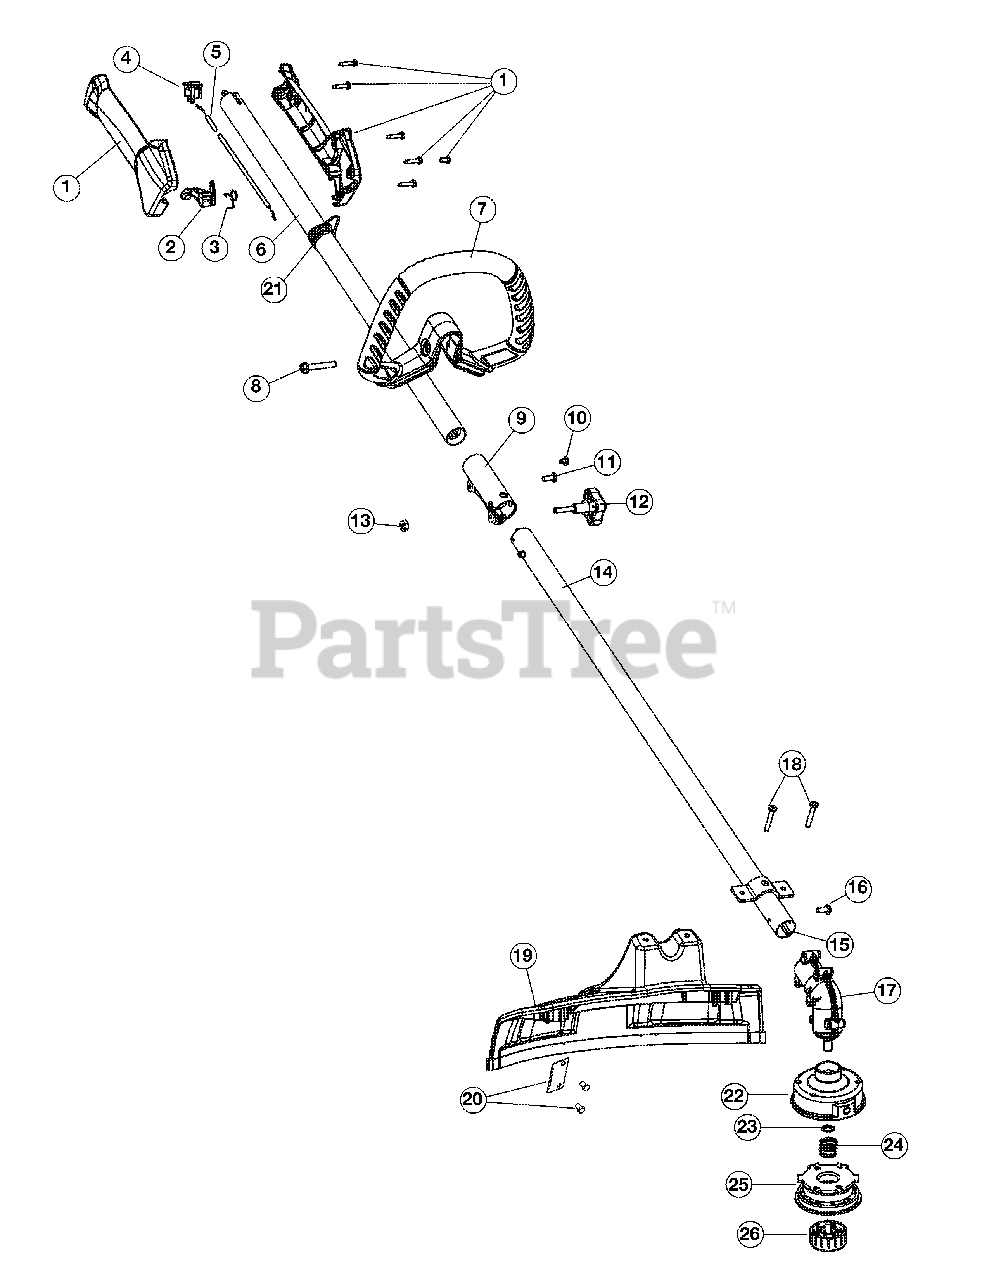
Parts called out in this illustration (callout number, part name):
1	Throttle Housing Assembly (Incl. Ref No. 2-4)
2	Throttle Trigger
3	Throttle Trigger Spring
5	Throttle Cable Assembly
6	Upper Drive Shaft Housing Assembly
7	Deluxe D-Handle Assembly (Incl.Ref No. 8)
9	Split Boom Coupler (Incl. Ref No.10-13)
12	Adjustment Knob (Incl. Ref No 13)
13	Knob Retaining Nut
14	Lower Drive Shaft Housing Assembly
15	Lower Flexible Drive Shaft
16	Anti-Rotation Screw
17	Gear Box Assembly (Incl. Ref No.16)
18	Shield Mounting Screws
19	Shield Assembly (Incl. Ref No.18 & 20)
20	Blade Assembly
21	Shoulder Strap Clip
22	Outer Spool Assembly
25	Inner Reel
26	Bump Knob Assembly
